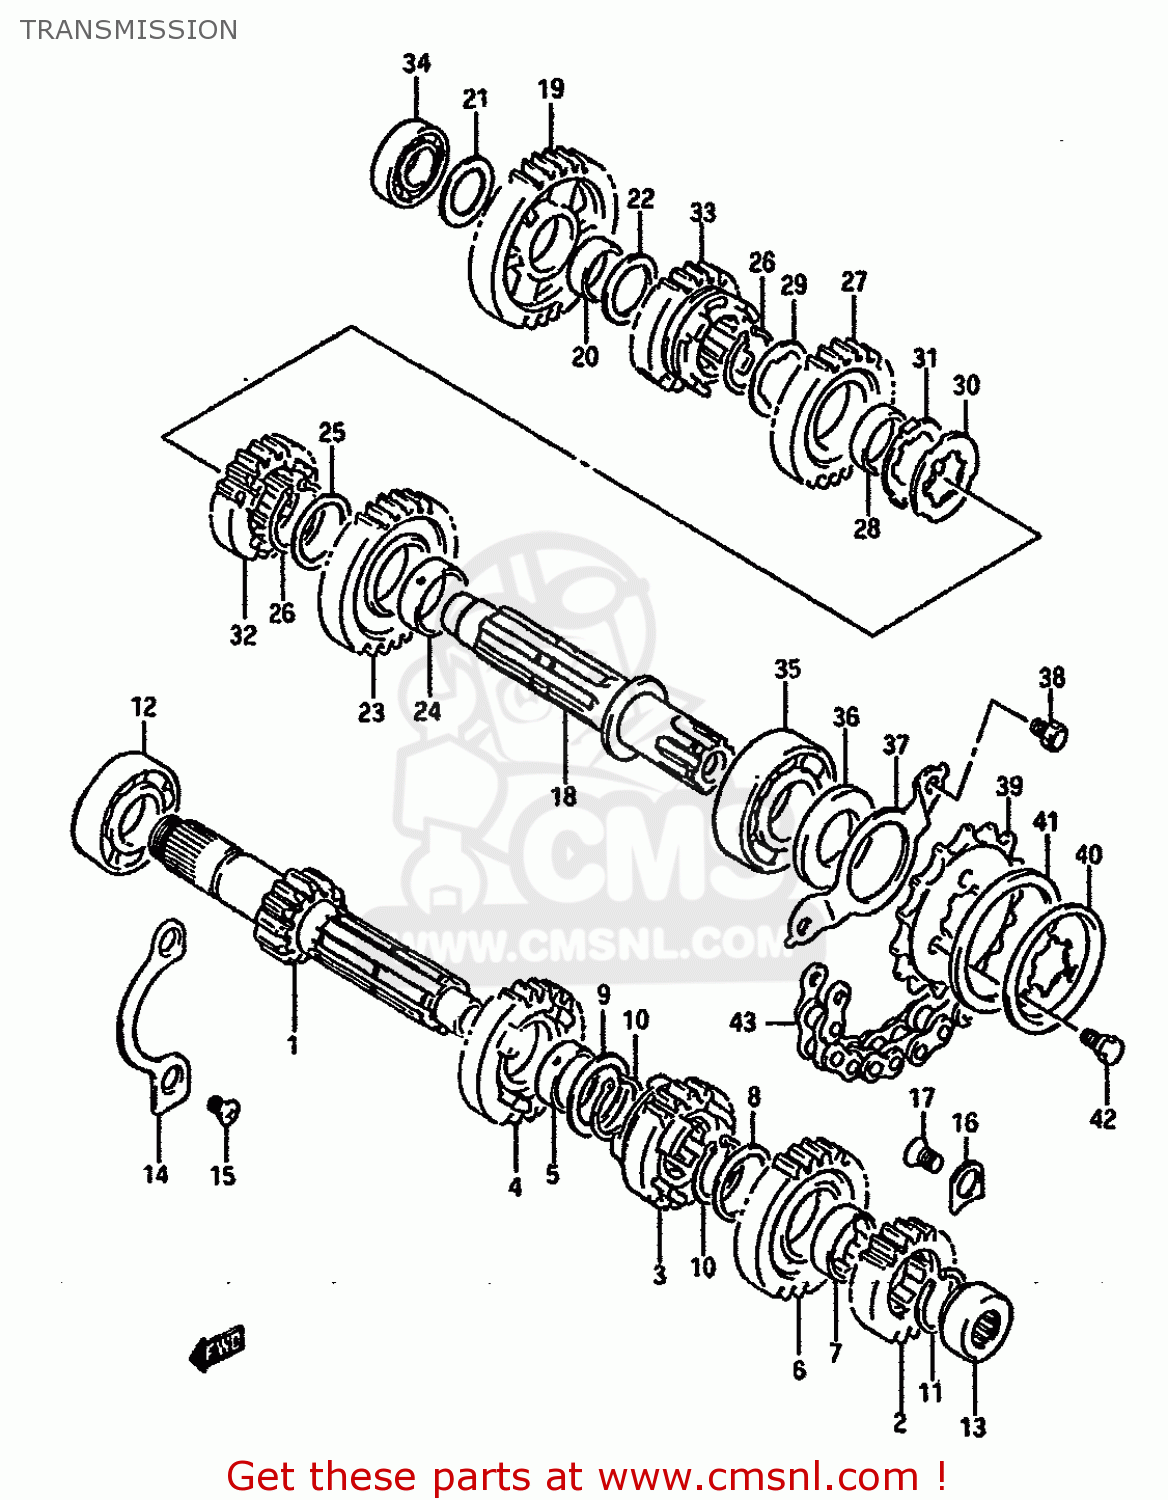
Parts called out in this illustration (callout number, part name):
1	COUNTERSHAFT (NT:13)
2	GEAR,2ND DRIVE (NT:19)
3	GEAR,THIRD DRIVE (NT:20)
4	GEAR,4TH DRIVE(NT:23)
5	BUSHING 25X29X10
6	GEAR,FIFTH DRIVE (NT:25)
7	BUSHING
8	WASHER,LOCK
9	WASHER
10	RING,SNAP
11	CIRCLIP
12	BEARING
13	BEARING(17X30X14)
14	RETAINER,CNTR SHAFT BEARING
15	SCREW
16	RETAINER
17	SCREW
18	SHAFT,DRIVE
19	GEAR,1ST DRIVEN (NT:32)
20	BUSHING
21	WASHER,THRUST
22	WASHER
23	GEAR,2ND DRIVEN (NT:30)
24	BUSH(28X32X11)
25	WASHER
26	CIRCLIP
27	GEAR,THIRD DRIVEN (NT:24)
28	BUSH
29	WASHER,LOCK
30	WASHER,LOCK
31	WASHER
32	GEAR,FOURTH DRIVEN (NT:22)
33	GEAR,5TH DRIVEN (NT:20)
34	BEARING(20X42X12)
35	BEARING(25X62X17)
36	SEAL,OIL(25X45X5)
37	RETAINER,DRIVESHAFT O
38	BOLT
39	SPROCKET,ENGINE(15T)
40	PLATE,ENGINE SPROCKET
41	DAMPER,ENGINE SPROCKET
42	BOLT(6X13)
43	CHAIN(DID520VL2,116L)
